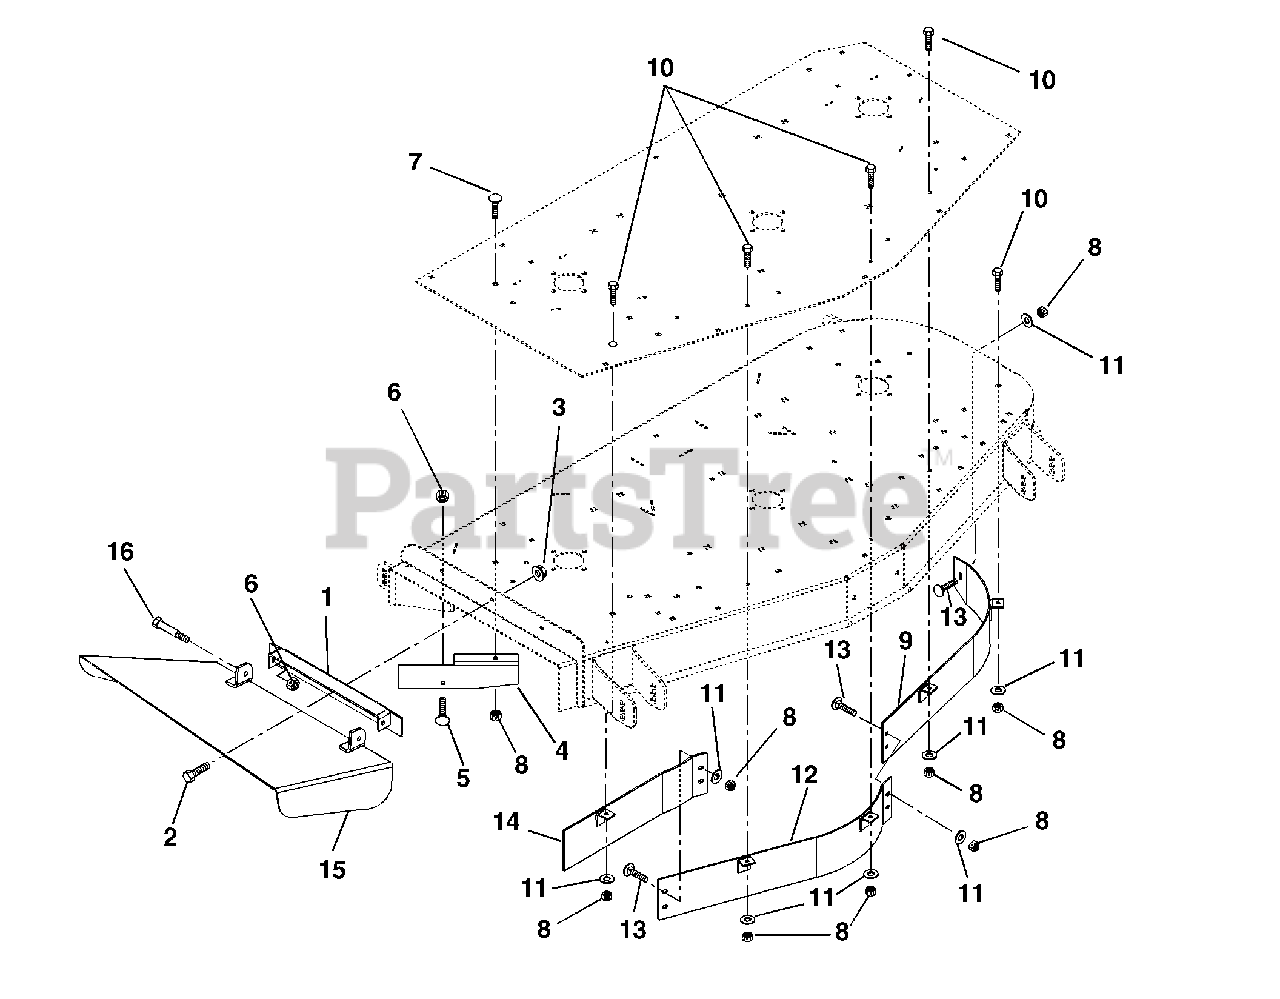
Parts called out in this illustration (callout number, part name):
1	Weldment, Discharge Chute Bracket
2	Bolt-Hex .38-16 x 1.00 Grade 5
3	Nut-Locking-Flange .38-16
4	Deflector, 72"
5	Bolt-Round Head Square Neck .38-16 x 1.00 Grade 2
6	Nut-Locking-Center .38-16
7	Bolt-Round Head Square Neck .31-18 x 1.00 Grade 5
8	Nut-Locking-Nylon .31-18
9	Weldment, 72" Left Hand Baffle
10	Bolt-Hex .31-18 x 1.00 Grade 5
11	Washer-Flat-Steel .312 x .734 x .065
12	Weldment, 72" Center Baffle
13	Bolt-Round Head Square Neck .31-18 x .75 Grade 2
14	Weldment, 72" Right Hand Baffle
15	Weldment, Discharge Chute 72"
16	Bolt-Shoulder .38-16 x .38
17	72" S.D. Mulch Kit
18	72" Discharge Cover Kit
